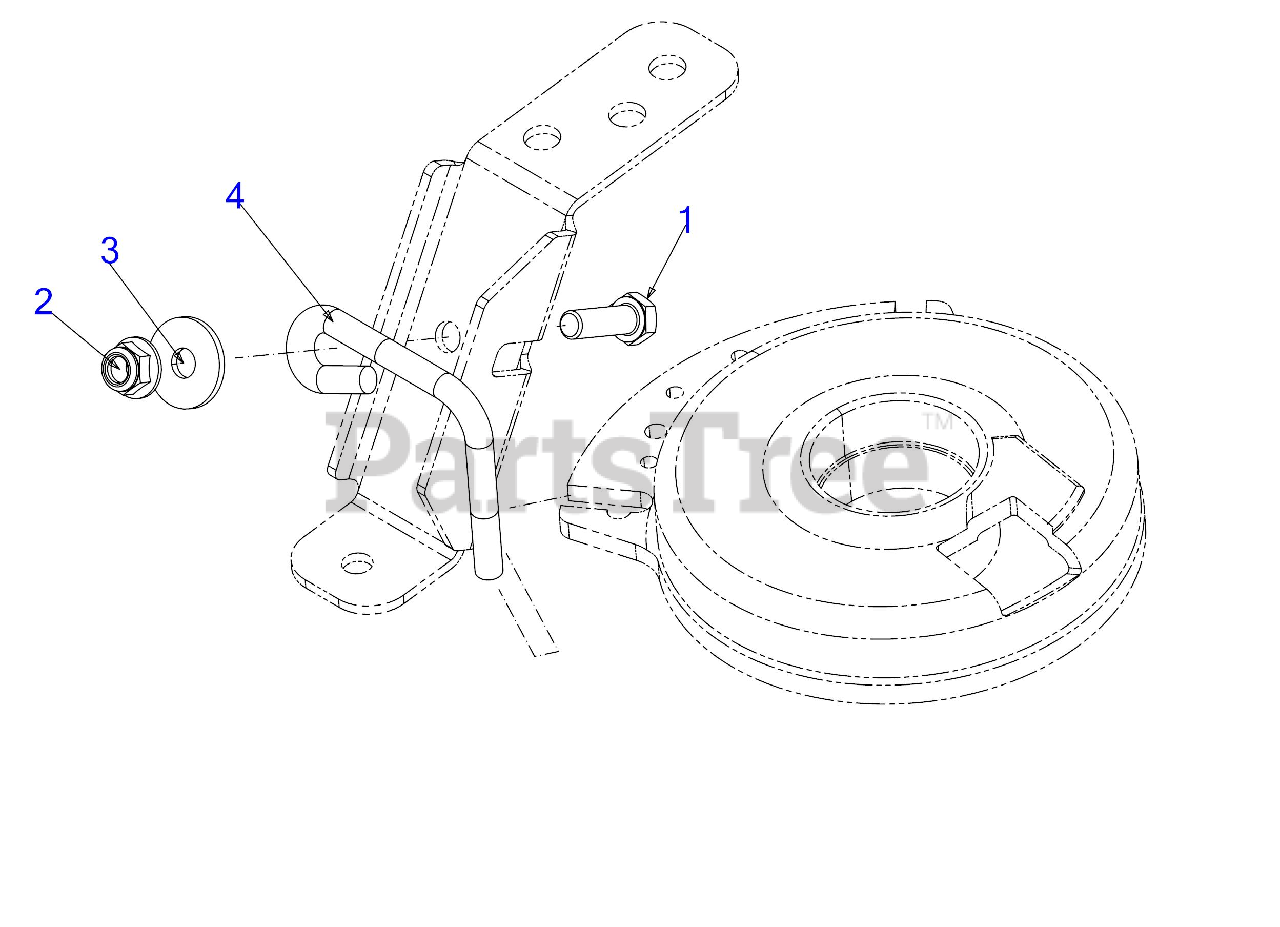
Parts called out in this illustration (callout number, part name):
1	SCREW 5/16-18 x 1.0 GR5
2	FLANGE LOCK NUT 5/16-18
3	FLAT WASHER 1.0 OD:.331 ID
4	CLUTCH KEEPER ROD
